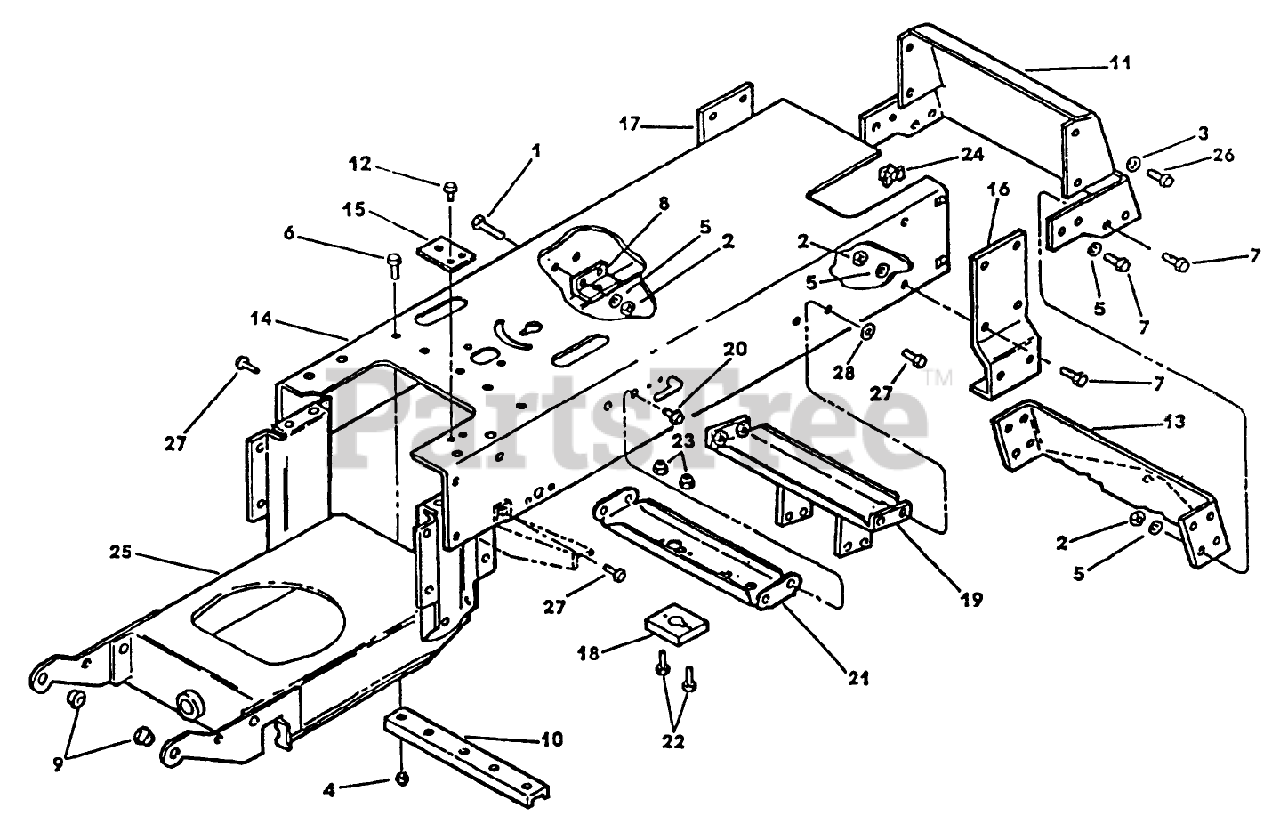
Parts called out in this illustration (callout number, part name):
2	NUT
4	NUT
5	WASHER
9	BEARING-NYLINER
18	BRACKET-SUPPORT *B
21	SUPPORT *B
22	SCREW
23	NUT-LOCK, CONE
24	NUT-SQ, CAGED
26	SCREW
